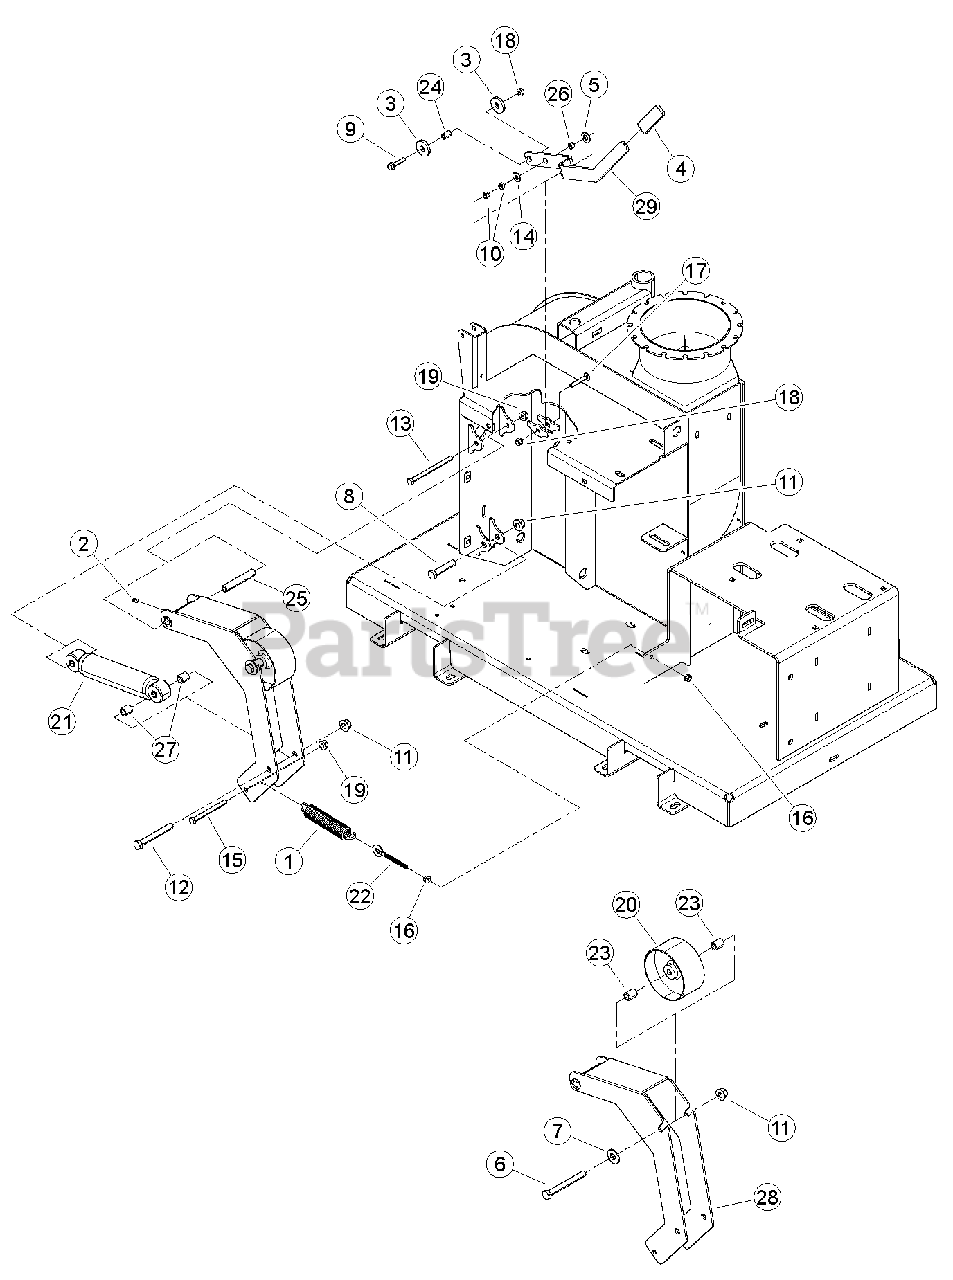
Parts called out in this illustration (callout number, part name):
1	SPRING, 9 GAUGE WIRE TENSION
2	FITTING, 1/4 SELF-TAP GREASE
3	WASHER, UHMW SPACER .515 ID-1.50 OD
4	GRIP, CLUTCH HANDLE
5	WASHER, 1/2 INCH NYLON
6	BOLT, 1/2 X 4-1/2" GR5 HHCS NC ZP
7	WASHER, 1/2 FLAT
8	BOLT, 1/2 X 2-1/2 GR5 HEX CAP ZP
9	BOLT, 5/16 X 1-1/2 FLANGE NC
10	NUT, 5/16 HEX NC - ZP
11	NUT, 1/2-13 NYLOCK FLANGE
12	BOLT, 1/2 X 4 HEX CPS G5 ZP
13	BOLT, 3/8 X 5" GR5 HEX CPS ZP
14	WASHER, 5/16 FLAT
15	BOLT, 3/8 X 4" HHCS GR5 NC ZP
16	NUT, 5/16-18 SERRATED FLANGE NC
17	BOLT, 5/16 X 2" GR5 NC ZP
18	NUT, 5/16-18 NYLOCK FLANGE
19	NUT, 3/8-16 NYLOCK FLANGE
20	PULLEY, IDLER 5" X 2.50"
21	ABSORBER, IDLER SHOCK
22	BOLT, 5/16 X 3-5/8" EYE
23	SPACER, .75 X .90
24	SPACER, .50 X .775
25	TUBE, PIVOT
26	SPACER, 1/2 OD X 14 GA WALL X .320
27	SPACER, IDLER SHEAVE
28	WELDMENT, IDLER ARM
29	HANDLE, ENGAGEMENT
